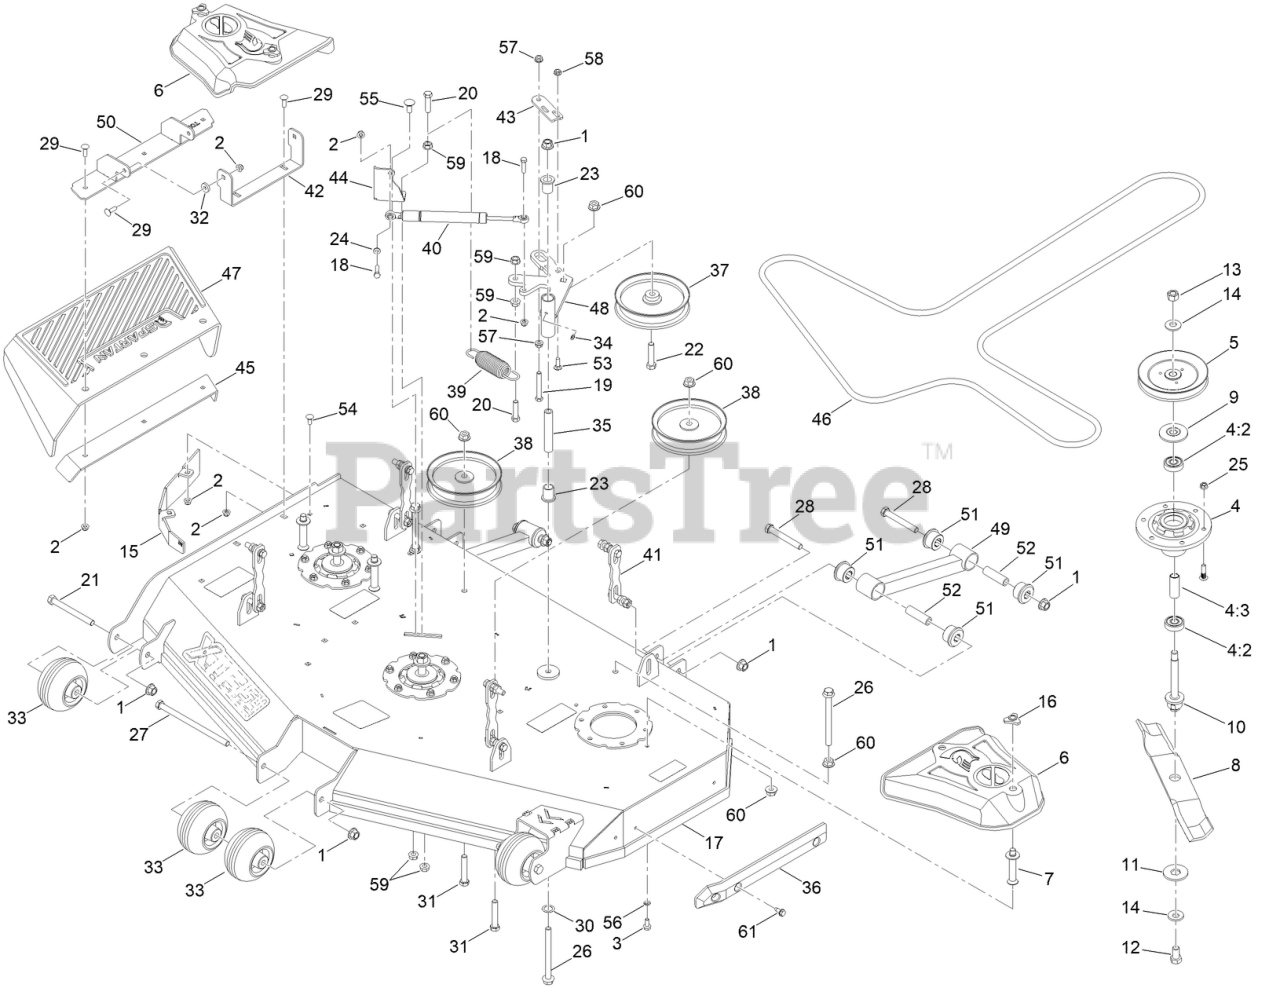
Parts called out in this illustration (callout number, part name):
1	NUT-LOCK
2	NUT-HF, NI
3	SCREW-HHF
4	SPINDLE ASM 5IN DECK
4:2	BEARING
4:3	SPACER, BEARING
5	PULLEY
6	COVER BELT
7	PIN-BELT COVER
8	BLADE-ROTARY
9	GUARD-BEARING TOP 0.673IN
10	SHAFT - SPINDLE
11	WASHER-HEX
12	M16X1.5-30MM C10.9 HEX BOLT
13	M16X1.5 C8.8 HEX NUT
14	M16 SPRING WASHER (39MMOD/ 3.9MM THK)
15	BAFFLE-WIPER 54 PAINTED
16	NUT-KNOB
17	ASM-DECK W/ DECALS
18	SCREW-HH
19	SCREW-HH
20	SCREW-HH
21	SCREW-HH
22	SCREW-HH
23	3/4IN ID X15/16IN OD X 1-1/8IN FLNG BUSH
24	.312IDX.625ODX.062 THK THRUST BRG OI BRZ
26	1/2-13 X 5-1/2 HEX FLANGE BOLT GR 8 ZY
27	1/2-13 X 8-1/2 HEX C/S GR 2 ZINC YELLOW
28	1/2-13 X 3-3/4 HEX C/S (GR.5) ZC/YEL
29	5/16-18 X 1 CARRIAGE BOLT GR 8 YZ
30	.767IDX1.125ODX.016 THK TRIP WV WASHER
31	1/2-13 X 2-3/4 HEX FLANGE BOLT (GR.8) YZ
32	.312 ID X .875OD X .1875 THK F/W NYL
33	MWR ANTI-SCALP WHL W/O GREASE FITTING
34	1/4IN DRIVE TYPE GREASE FITTING YZ
35	MWR INNER IDLER SPACER
36	MWR NYLON DECK GUARD
37	6-3/4IN IDLER PULLEY 7/16IN SPACER ASM
38	6-3/4IN IDLER PULLEY 15/16IN SPACER ASSY
39	MWR DECK SPRING
40	IDLER GAS SPRING
41	RZ MWR DECK LINK ASM
42	MWR CHUTE MTG BRKT PAINTED
43	DECK IDLER PULLEY BELT RETNR BRKT PAINT
44	DECK BELT IDLER DAMPER MTG BRKT PAINTED
45	RZ MWR DECK CHUTE HNGE BACKR BRKT PAINT
46	54 DECK BELT
47	RZ MWR RUBBER DISCHARGE CHUTE
48	MWR DECK IDLER PULLEY ARM ASSY PAINT
49	RZ MWR DECK STABILIZER ASSY PAINTED
50	2020 RZ MWR DECK CHUTE HINGE ASSY PAINT
51	RED A80 SUSP BUSHING
52	UTV A-ARM BUSHING SLEEVE
53	BOLT-CARR
54	3/8-16 X 1 CARRIAGE BOLT YZ GR.8
55	SCREW-CARR
56	WASHER-LOCK
57	3/8-16 HEX FLANGE NUT W/SERR ZINC YELLOW
59	NUT-HF
60	NUT-HHF
61	SCREW-HWH, THREAD CUT
